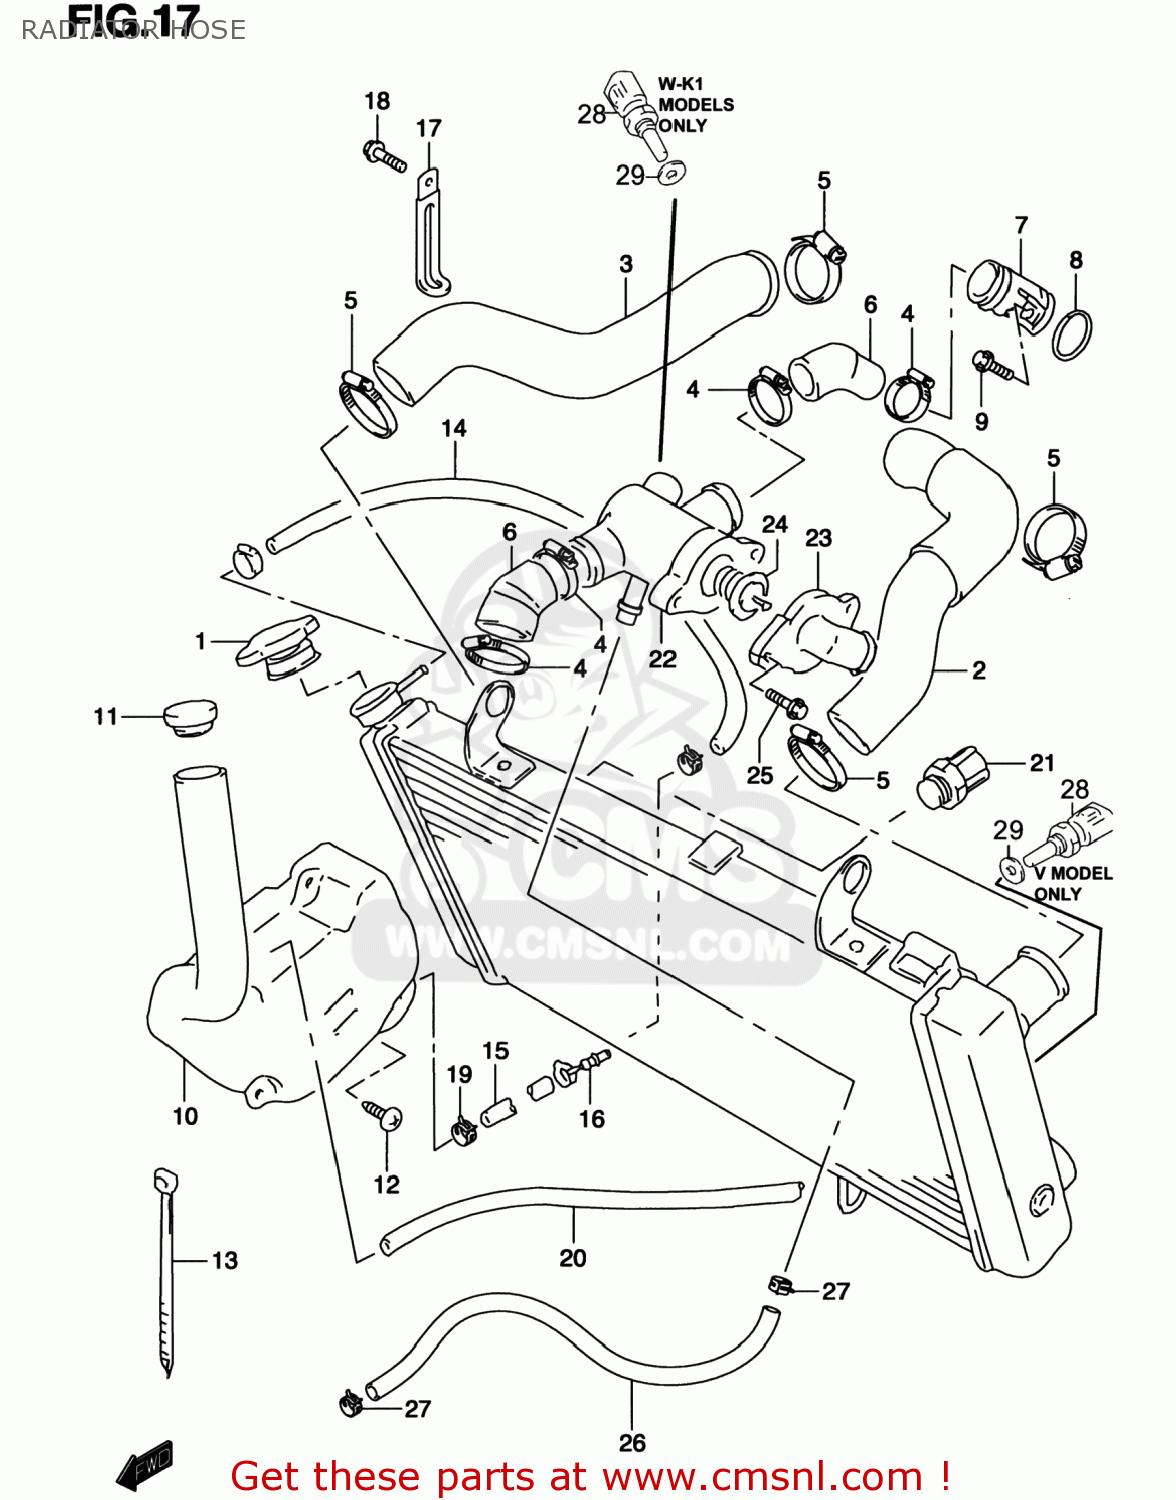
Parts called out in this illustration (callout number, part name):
1	CAP,RADIATOR
2	HOSE,RADIATOR INLET
3	HOSE,RADIATOR OUTLET
4	CLAMP
5	CLAMP
6	HOSE,CONNECTOR INLET
7	UNION,CONNECTOR HOSE
8	O RING(D:3.2,ID:17.8)
9	BOLT,STRANGER
10	TANK ASSY,RESERVOIR
11	CAP,RESERVOIR TANK
12	SCREW(5X16)
13	CLAMP
14	HOSE(5X9X600)
15	HOSE(5X9X600)
16	UNION
17	CLAMP(L:65)
18	SCREW 5X8
19	CLIP
20	HOSE(5X9X600)
21	SWITCH,RADIATOR FAN
22	CONNECTOR,THERMOSTAT,INLET
23	CAP,THERMOSTAT CONNECTOR
24	THERMOSTAT,WATER
25	BOLT
26	HOSE,CONNECTOR TO WATER
27	CLAMP
28	SENSOR,WATER TEMP
29	GASKET(12.2X21X0.8) (NAS)
